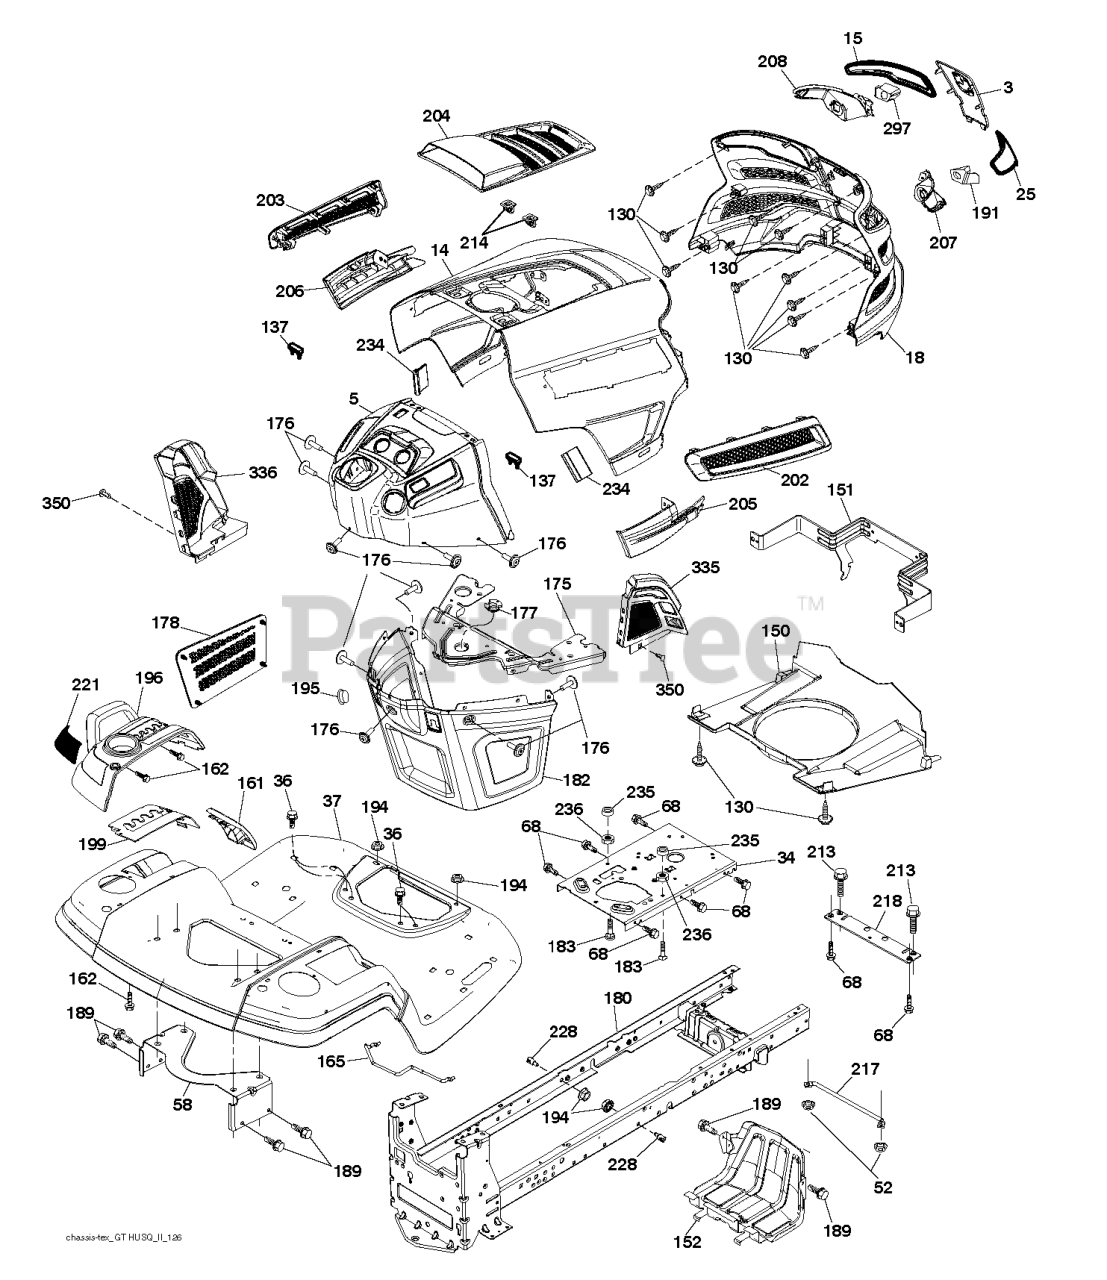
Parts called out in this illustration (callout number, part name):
3	APPLIQUE.SUBASM.GT.HUSQ.II
5	DASH.UPP.GT2.SM.PTO.MCHOKE
14	HOOD.ASM.HUSQVARNA.GT.TEX.ORAN
15	LENS.HEADLIGHT.LH.GTII.2011
18	GRILLE.SUBASM.GT.HUSQ.II
25	LENS.HEADLIGHT.RH.GTII.2011
34	PLATE PLATE ENGINE
36	SCREW 5/16"
37	FENDER.PNT.TX.GT.CH/FW/DL.HUSQ
52	LOCKNUT
58	BRKT.SUPPORT.FNDR/TANK
68	SCREW LT
130	SCREW.#10 X 0.750.BOS
137	BUMPER DASH
150	AIR.DUCT.GTV.BLACK
151	BRACKET.PIVOT.HOOD.GT.HUSQ.II
152	SHIELD.BROWNING.PNT.GT.V2
161	CONSOLE.WINDOW.FUEL.HUSQ.GT
162	SCREW.HI-LO.CONSOLE
165	SUPPORT.TANK.REAR.W/TEX
175	PLATE.CROSSMEMBER.HUSQ
176	SCREW.#10-24X5/8.RN.QU
177	BUSHING, STEERING
178	CARGO.ASM.NET.TXGT.W/C
180	CHASSIS.GT.SLOPED.DRAWBAR.
182	DASH.LOWER.COMMON.12V.ADAPTOR
183	BOLT.5/16-18X1-1/4 FULL THD
189	SCREW
191	INSERT.REFLECTIVE.RH.HUSQ.GTII
194	NUT LOCK HEX FLANGE 5/16-18
195	PLUG.HOLE.DASH.LOWER.12V.BLK
196	SUBASM.CONSOLE.HUSQ.GT.DECKLFT
199	PLATE.DECK.LIFT.HUSQVARNA.GT
202	VENT.SIDE.RH.GT.HUSQ.II.
203	VENT.SIDE.LH.GT.HUSQ.II.498
204	VENT.TOP.HUSQ.GT2
205	SIDE.TRIM.RH.GT.HUSQ.II
206	SIDE.TRIM.LH.GT.HUSQ.II.GRAY
207	BEZEL LIGHT.RH.GT.II.MYLAR
208	BEZEL LIGHT.LH.GT.II.MYLAR
213	BOLT
214	CLIP.RETAINER.TINNER.
217	ROD.PIVOT.HOOD
218	X-PIECE.HOOD.STOP.NON/
221	REFLECTOR.LH.TEX GT HU
228	STUD.FASTNER.W/ANTI-ROTATE
234	BUMPER.HOOD.TEX.HUSQVARNA
235	SPACER FENDER
236	NUT.CENTERLOCK.5/16-
297	INSERT.REFLECTIVE.LH.HUSQ.GTII
335	COVER.LOWER.DASH.RH.BLACK
336	COVER-LH.LOWER.DASH.GT2.BLACK
350	CLIP.X-MAS.TREE
